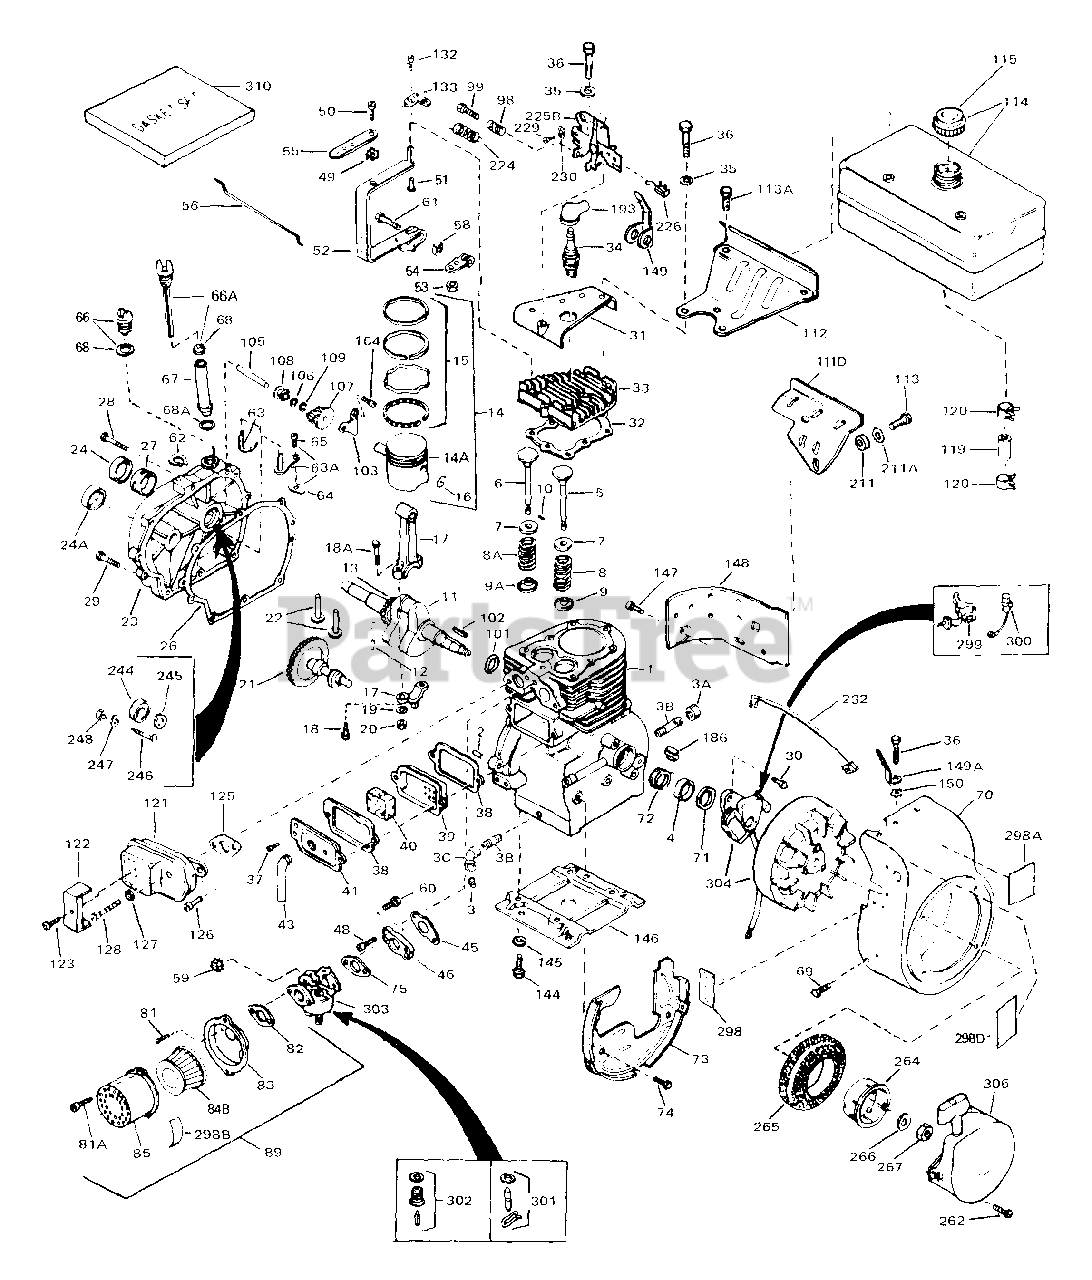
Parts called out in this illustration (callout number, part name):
1	"Cylinder Assy. (2-5/8" Bore)
2	Pin, Dowel
3	Plug, Oil drain (Sq. hd. 1/4-18)
4	Seal, Oil
5	Valve, Intake (Std.)
5	Valve, Intake (1/32" oversize)
6	Valve, Exhaust (Std.)
6	Valve, Exhaust (1/32" oversize)
7	Cap, Upper valve spring
8	Spring, Valve
8A	Spring, Valve
9	Cap, Lower valve spring
9A	Cap, Lower valve spring
11	Crankshaft Assy.
12	Pin, Crankshaft gear
13	Gear, Crankshaft
14	Piston, Pin & Ring Assy. (Std.) (2-5/ 8")
14	Piston, Pin & Ring Assy. (.010 oversi ze)
14	Piston, Pin & Ring Assy. (.020 oversi ze)
14A	Piston & Pin Assy. (Std.) (2-5/8")
14A	Piston & Pin Assy. (.010 oversize)
14A	Piston & Pin Assy. (.020 oversize)
15	Ring Set, Piston (Std.) (2-5/8")
15	Ring Set, Piston (.010 oversize)
15	Ring Set, Piston (.020 oversize)
16	Ring, Piston pin retaining
17	Rod Assy., Connecting
18	Screw, Connecting rod
18A	Bolt, Connecting rod
19	Washer, Connecting rod bolt
20	Nut, Connecting rod
21	Camshaft (Compression Release)
22	Lifter, Valve
23	Cover, Cylinder
26	Gasket, Cylinder cover
31	Cover, Cylinder head
32	Gasket, Cylinder head
33	Head, Cylinder
34	Plug, Spark (Champion J-8 or equivale nt)
34	Resistor Spark Plug
35	Washer, Flat
36	Screw, Hex flange hd., 5/16-18 x 2
36	Screw, Hex flange hd., 5/16-18 x 2-1/ 4
36	Screw, Hex flange hd., 5/16-18 x 2-1/ 2
37	Screw, Fil. hd. Sems, 10-24 x 1/2
37	Screw, Hex washer hd., 10-24 x 5/8
38	Gasket, Breather cover
39	Body, Breather
40	Element, Breather
41	Cover, Valve spring
43	Tube, Breather
45	Gasket, Intake
46	Flange, Carburetor
49	Lockwasher
50	Screw, Hex washer hd., 8-32 x 5/16
51	Rivet,Split
52	Lever, Governor
53	Nut & Lockwasher, 8-32
54	Clamp, Governor lever
55	Bracket, Adjusting
56	Link, Throttle
58	Locknut, Hex "Keps"
59	Nut & Lockwasher
60	Screw
62	Ring, Retaining
63	Rod Assy., Governor
63A	Rod Assy., Governor
64	Yoke, Governor
66A	Dipstick, Oil (Screw In)
68	Gasket, Dipstick
69	Screw
70	Housing, Blower (5.56 Dia. starter mt g. bolt
73	Baffle, Blower housing
75	Gasket, Carburetor (1/8" thick)
81	Screw, Fil. hd. Sems, 10-32 x 1/2
81	Screw, Fil. hd., 5/16-18 x 3/4
81	Screw, Fil. hd. Sems, 10-32 x 1-1/8
82	Gasket, Air cleaner
83	Bracket, Air cleaner
84B	Element, Air cleaner
85	Body, Air cleaner
89	Cleaner Assy., Air
98	Spring, Compression
99	Screw, Hex hd., 10-32 x 1 (Drilled th ru)
99	Screw, Fil hd., 5-40 x 7/16
102	Key, Flywheel
103	Bracket, Governor gear
104	Screw, Hex washer hd. thread forming, 10-24
105	Shaft, Mechanical governor
106	Washer, Flat
107	Gear Assy., Governor
108	Spool, Governor
109	Ring, Retaining
114	Tank Assy., Fuel (Charcoal Poly) (1 g al.)
115	Cap, Fuel filler (Red Plastic) (Spurt
115	Cap, Fuel filler (White Plastic) (Sta ndard)
119	Line, Fuel (Braided 8.25")
119	Line, Fuel (Braided 16")
119	Line, Fuel (Braided 32")
120	Clamp, Fuel line
121	Muffler
125	Gasket, Exhaust
127	Washer, Flat
128	Screw, Hex, flange hd., 5/16-18 x 2
132	Screw, Hex washer hd., 8-32 x 5/16
146	Base, Engine mounting
148	Extension, Blower housing
149A	Clip, Shorting
150	Lockwasher
186	Clip, Wire
186	Clip, Fuel line
224	Spring, Extension
225B	Bracket Assy., Speed control
226	Terminal Assy.
264	Cup, Starter
265	Screen, Starter cup
266	Washer, Belleville
267	Nut, Hex
298	Decal, Instruction
298A	Decal, H.P. (5 H.P.)
298A	Decal, H.P. (6 H.P.)
298A	Decal, Mini-Bike (5 H.P.)
298A	Decal, Name
298B	Decal, Air cleaner
299	Contact Assy., Breaker
300	Condenser
301	Inlet Needle, Seat & Clip Assy.
303	Carburetor
304	Magneto, Tecumseh
306	Starter, Rewind
310	Gasket Set
